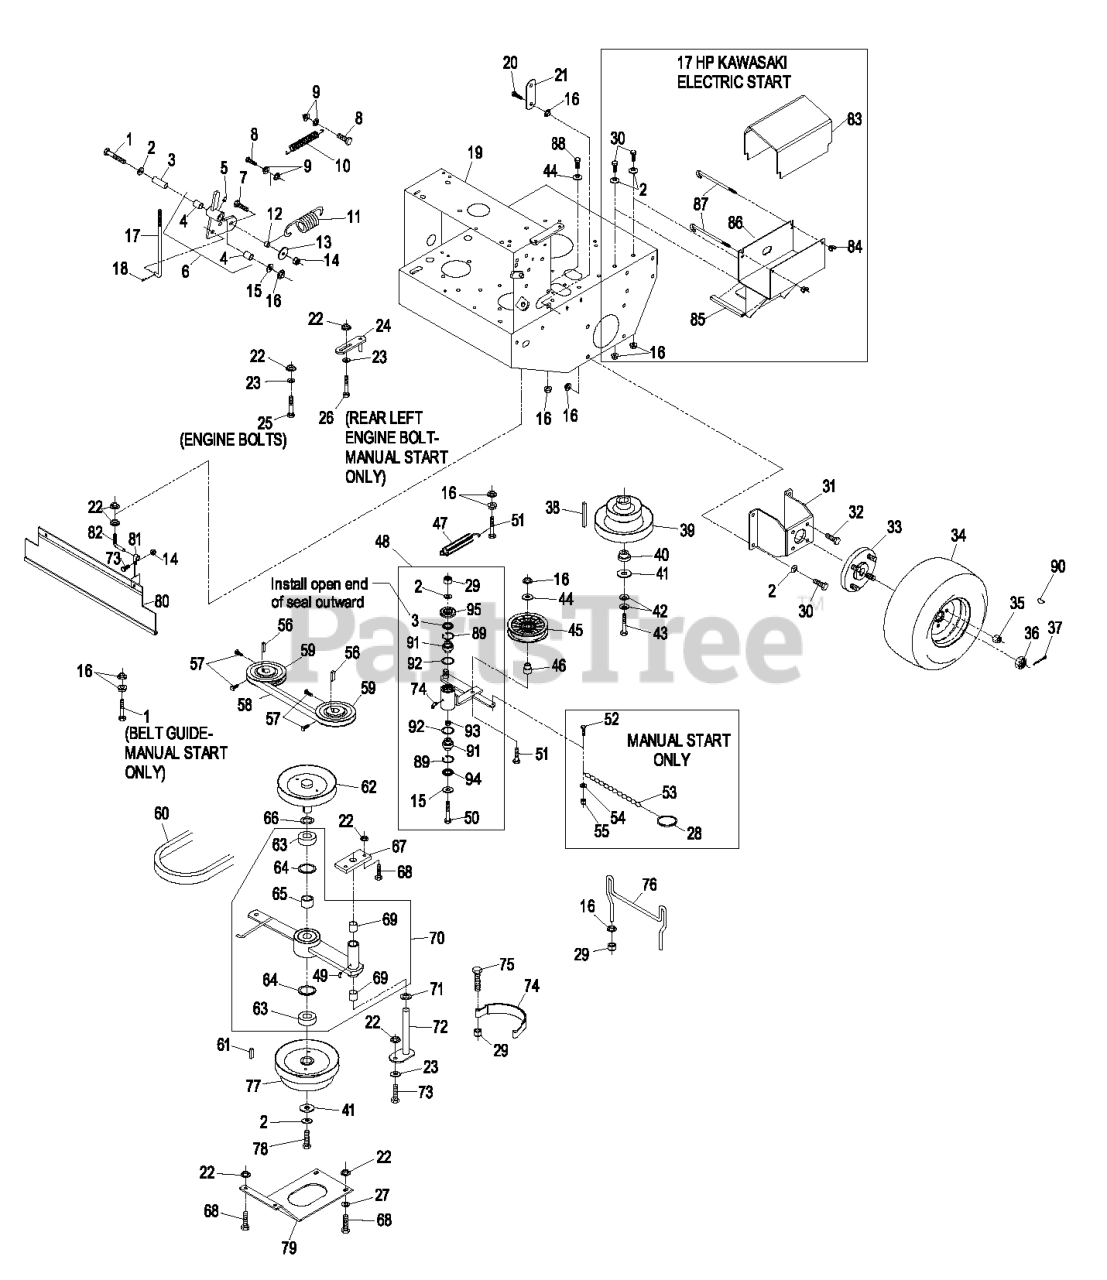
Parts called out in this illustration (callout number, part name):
1	SCREW-HH
2	WASHER-BELLEVILLE
3	SEAL-LIP, SINGLE
4	SLEEVE-BEARING
5	FITTING-GREASE
6	ASM,PIVOT W/BUSHINGS
7	SCREW-HH
8	SCREW-HH
10	SPRING,EXTENSION
11	SPRING,EXTENSION
12	SPACER,CLUTCH ANCHOR
14	NUT-LOCK, NI
15	WASHER-FLAT
16	NUT-HHF, WHIZ
17	LINKAGE,LOWER
18	PIN-COTTER
19	KIT,TTHP ENG DECK
20	SCREW-HH
21	ARM-LIFT, DECK
23	WASHER-SPRING
24	GUIDE-BELT
25	SCREW-HH
26	SCREW-HH
27	WASHER-FLAT
28	RING-SPLIT
29	NUT-LOCK, NI
30	SCREW-HH
31	WLD,MOTOR MOUNT 36
32	SCREW-HHF
34	WHEEL AND TIRE ASM
35	NUT-LUG
36	NUT-HEX, SLOTTED
37	PIN-COTTER
38	KEY,MACH 1/4X1/4X2-5/8
39	SHEAVE, DRIVE
40	BUSHING,CLUTCH KEEPER
42	WASHER-SPRING
43	SCREW-HH
44	WASHER-FLAT
45	PULLEY-IDLER, FLAT
46	BUSHING-IDLER
48	KIT,PUMP IDLER ARM TTHP
49	FITTING-GREASE
50	SCREW-HH
51	SCREW-HH
52	SCREW-HSH
53	CHAIN-LINK, TWIST
54	WASHER-FLAT
55	NUT-LOCK, NI
57	SCREW-SET
58	BELT,COG A 50.55
59	SHEAVE ASM
60	BELT,B-38.0
62	SHEAVE, W/ SHAFT
63	BEARING,CLUTCH SHAFT
64	RING-SNAP
65	SPACER,CLUTCH BEARING
66	WASHER-SPACER
67	PLATE-CLUTCH PIVOT
68	SCREW-HH
69	SLEEVE,BEARING
70	ASM,CLUTCH ARM W/BEARING
71	WASHER-SPACER
72	WLD,PIN PIVOT
73	SCREW-HH
74	BAND,BRAKE BLADE
75	SCREW-HH
76	GUIDE,BELT (PLTD)
77	SHEAVE,6.13 W/HUB
78	SCRW,CAP HH
79	PLATE-GUARD
80	SHIELD-DRAG
81	CLIP-LOOM
82	MOUNT,DRAG SHIELD
83	COVER,BATTERY W/DECAL
84	WINGNUT
85	TRIM-LOK
86	ASM,BATTERY STAND W/TRIM
87	BOLT - HOLD DOWN
88	SCREW-HH
89	RING-SNAP
90	KEY-WOODRUFF
91	BEARING-SPHERICAL
94	SEAL-LIP, DOUBLE
95	GUARD-TOP
